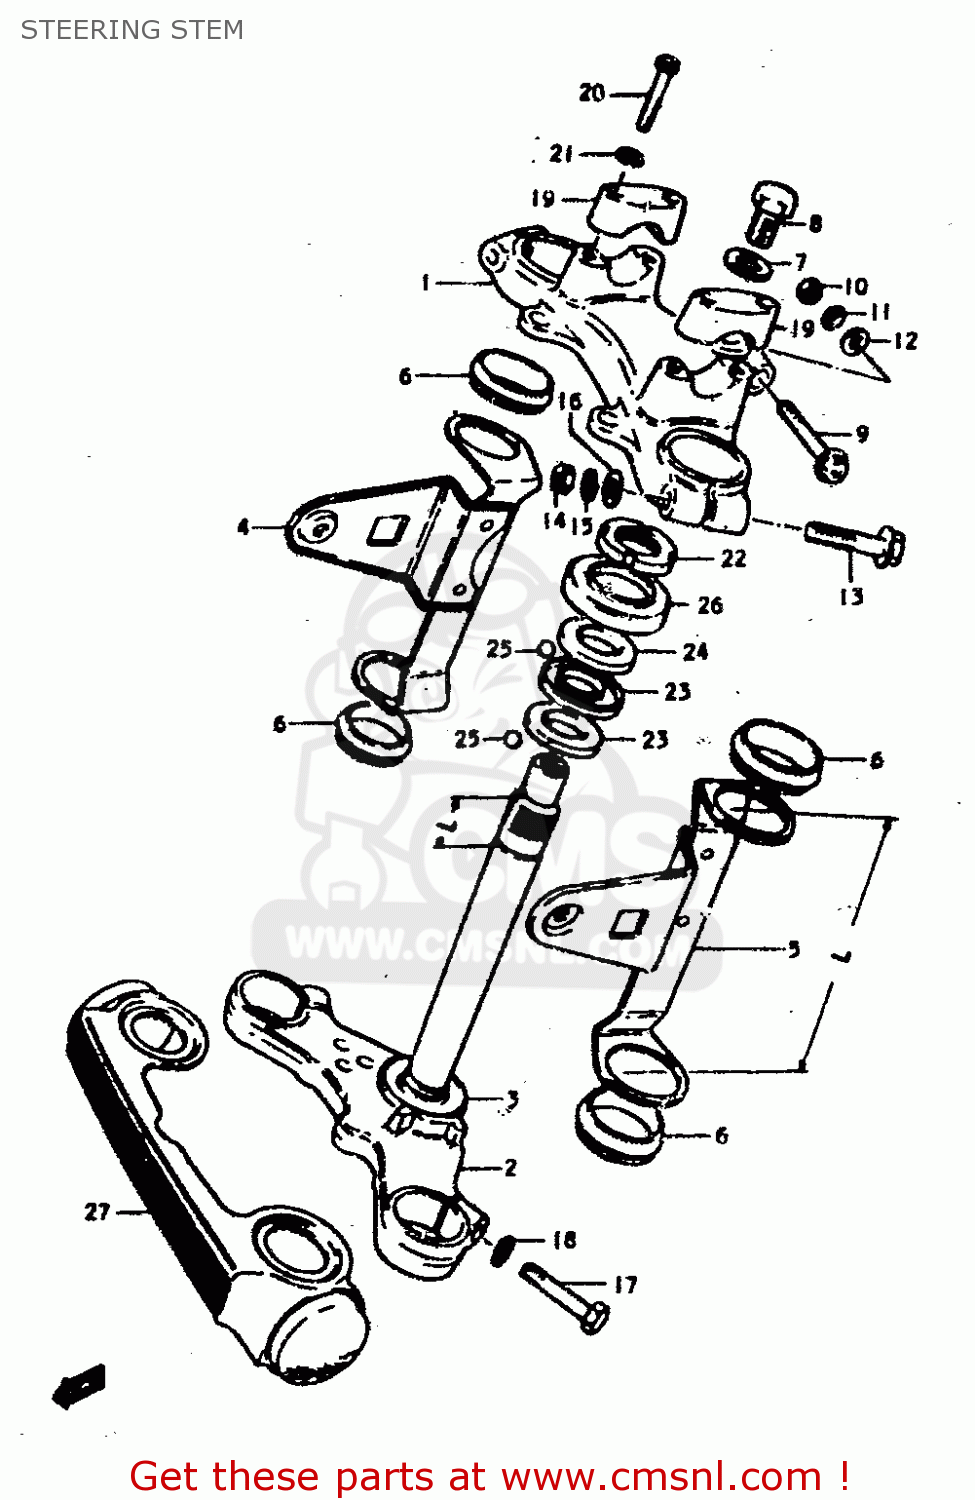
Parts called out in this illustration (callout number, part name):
1	HEAD,STEERING STEM
2	STEM,STEERING
3	RACE,STEERING OUTER LWR
4	BRACKET,HEADLAMP,RIGHT
5	BRACKET,HEADLAMP,LEFT
6	CUSHION,HEADLAMP BRACKET
7	WASHER
8	BOLT(12X20)
9	BOLT
10	NUT
11	LOCK WASHER
12	WASHER
13	BOLT
14	NUT
15	LOCK WASHER
16	WASHER
17	BOLT 10X40
18	LOCK WASHER
19	HOLDER,HANDLE UPR
20	BOLT
21	LOCK WASHER
22	NUT,STEERING STEM(25X44X10)
23	LACE,STEERING INNER LWR
24	LACE,STEERING OUTER UPR
25	BALL
26	DUST SEAL,STEERING UPR
27	COVER,FR FORK
